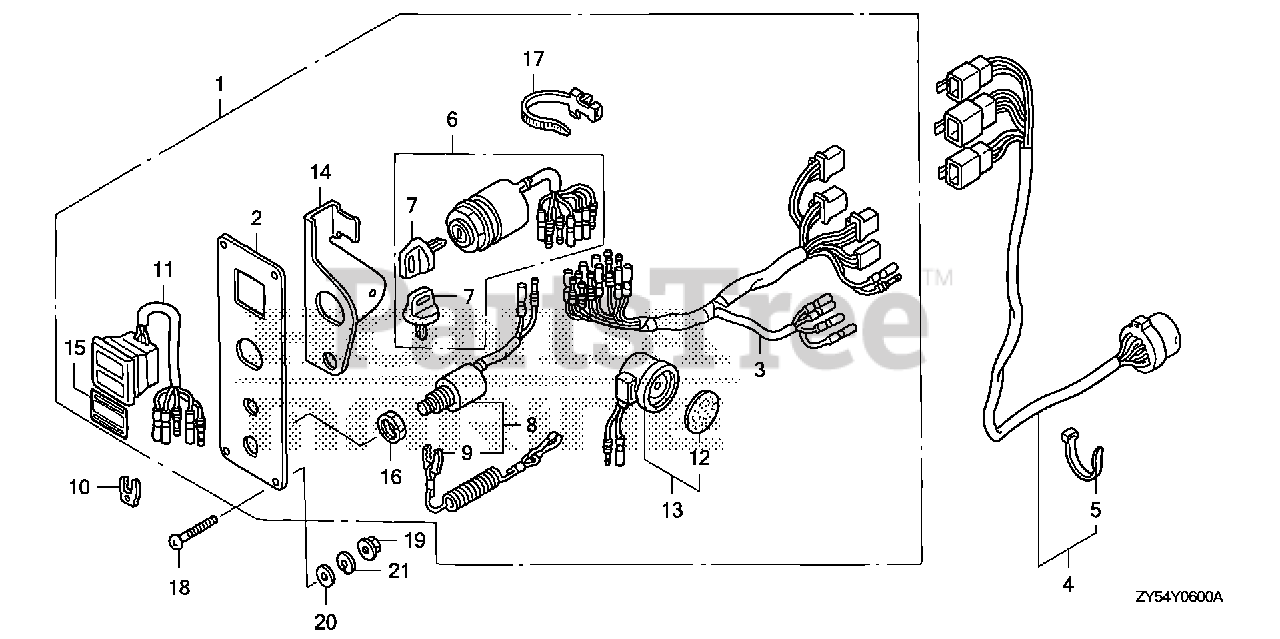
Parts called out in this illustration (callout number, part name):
1	PANEL ASSY., CONTROL (2-LED)
2	PANEL, CONTROL
3	HARNESS ASSY., SWITCH PANEL
4	CABLE ASSY., SWITCH PANEL
5	TIE, CABLE (2.4X92) (NATURAL)
6	SWITCH ASSY., COMBINATION
7	KEY ASSY., COMBINATION SWITCH (35100-ZV5-003 ONLY)
8	SWITCH ASSY., EMERGENCY STOP
9	WIRE, EMERGENCY
10	CLIP, EMERGENCY LOCK
11	LAMP ASSY., INDICATION (2-LED)
12	PLATE, TURN SIGNAL BUZZER
13	BUZZER, WARNING
14	BRACKET, BUZZER
15	MARK, SWITCH PANEL
16	NUT, HEX. (16MM)
17	BAND, WIRE HARNESS (150MM) (NATURAL)
18	SCREW, PAN (5X40)
19	NUT, FLANGE (5MM)
20	WASHER, PLAIN (5MM)
21	WASHER, SPRING (5MM)
